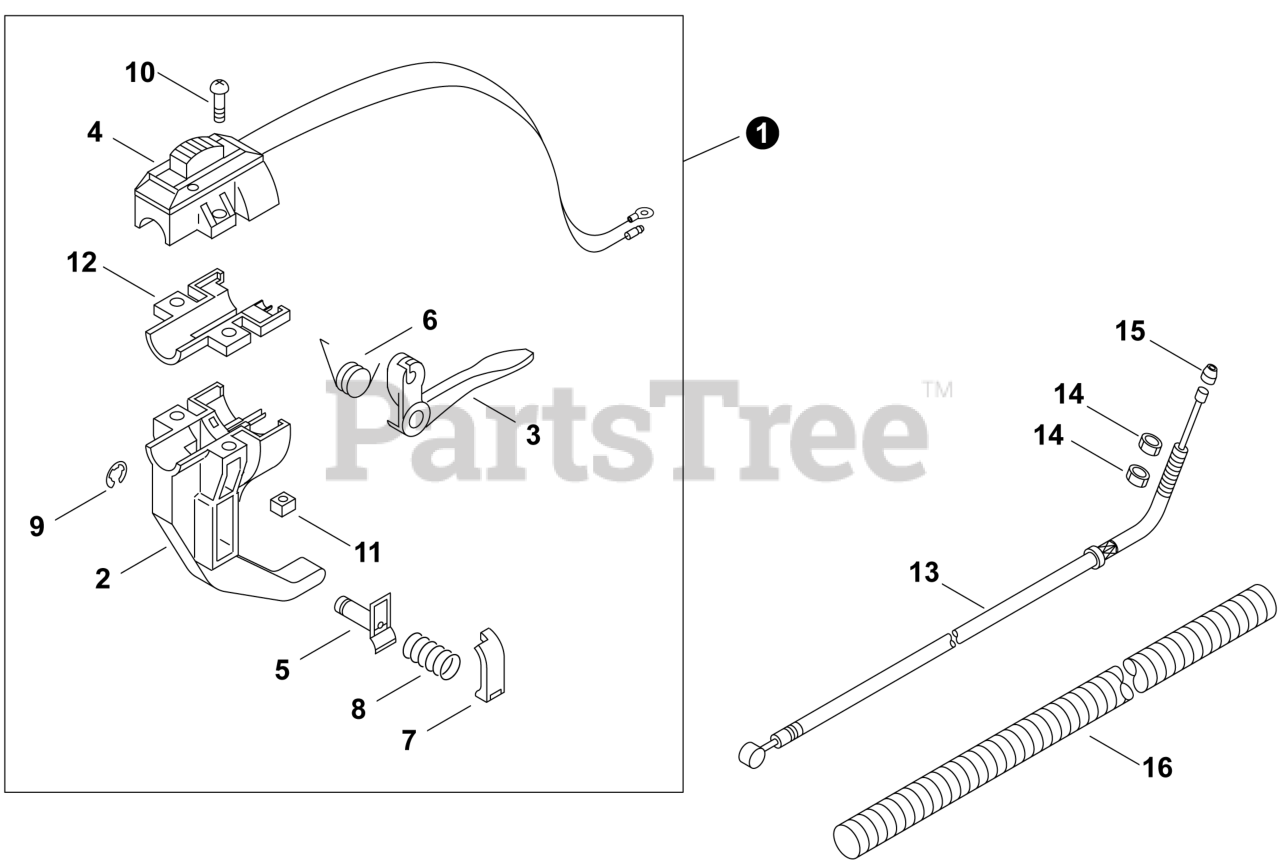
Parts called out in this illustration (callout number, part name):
1	TRIGGER ASSY, THROTTLE
2	BRACKET, THROTTLE
3	TRIGGER, THROTTLE
4	COVER ASSY
5	SHAFT, THROTTLE
6	SPRING, RETURN
7	LATCH, THROTTLE
8	SPRING, TORSION
9	E-RING
12	HOLDER, CABLE
13	CABLE, THROTTLE
15	CAP, DUST
